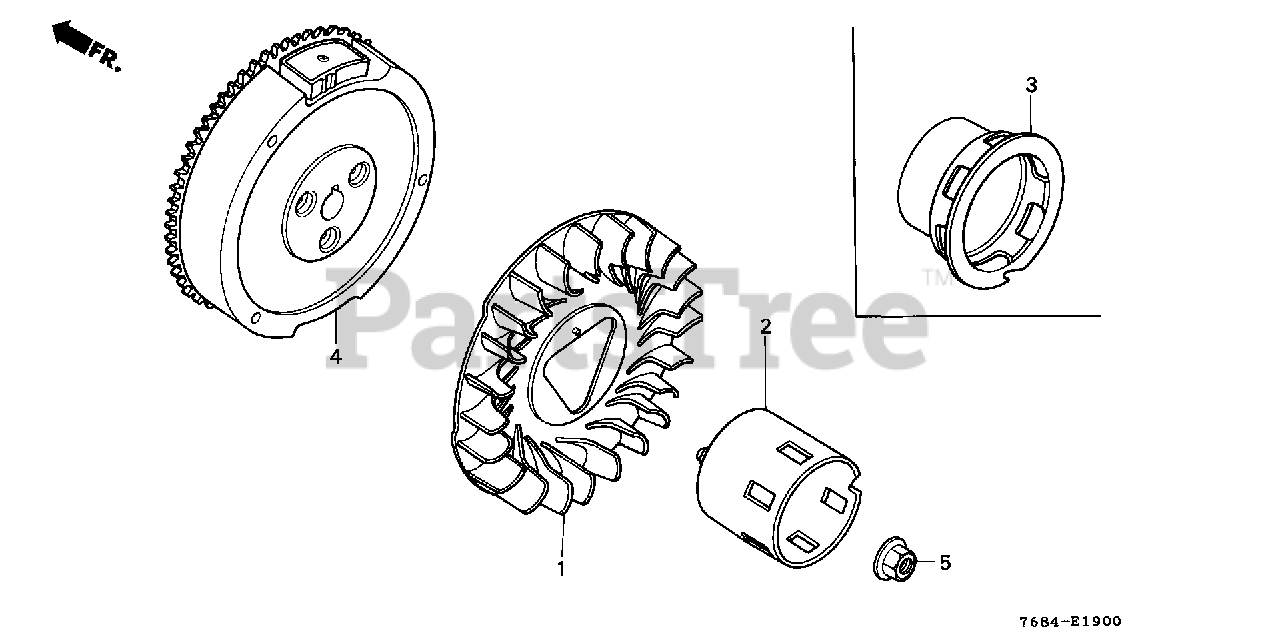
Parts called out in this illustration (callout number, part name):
1	FAN, COOLING
2	PULLEY, STARTER
4	FLYWHEEL (LAMP)
5	NUT, SPECIAL (16MM)
